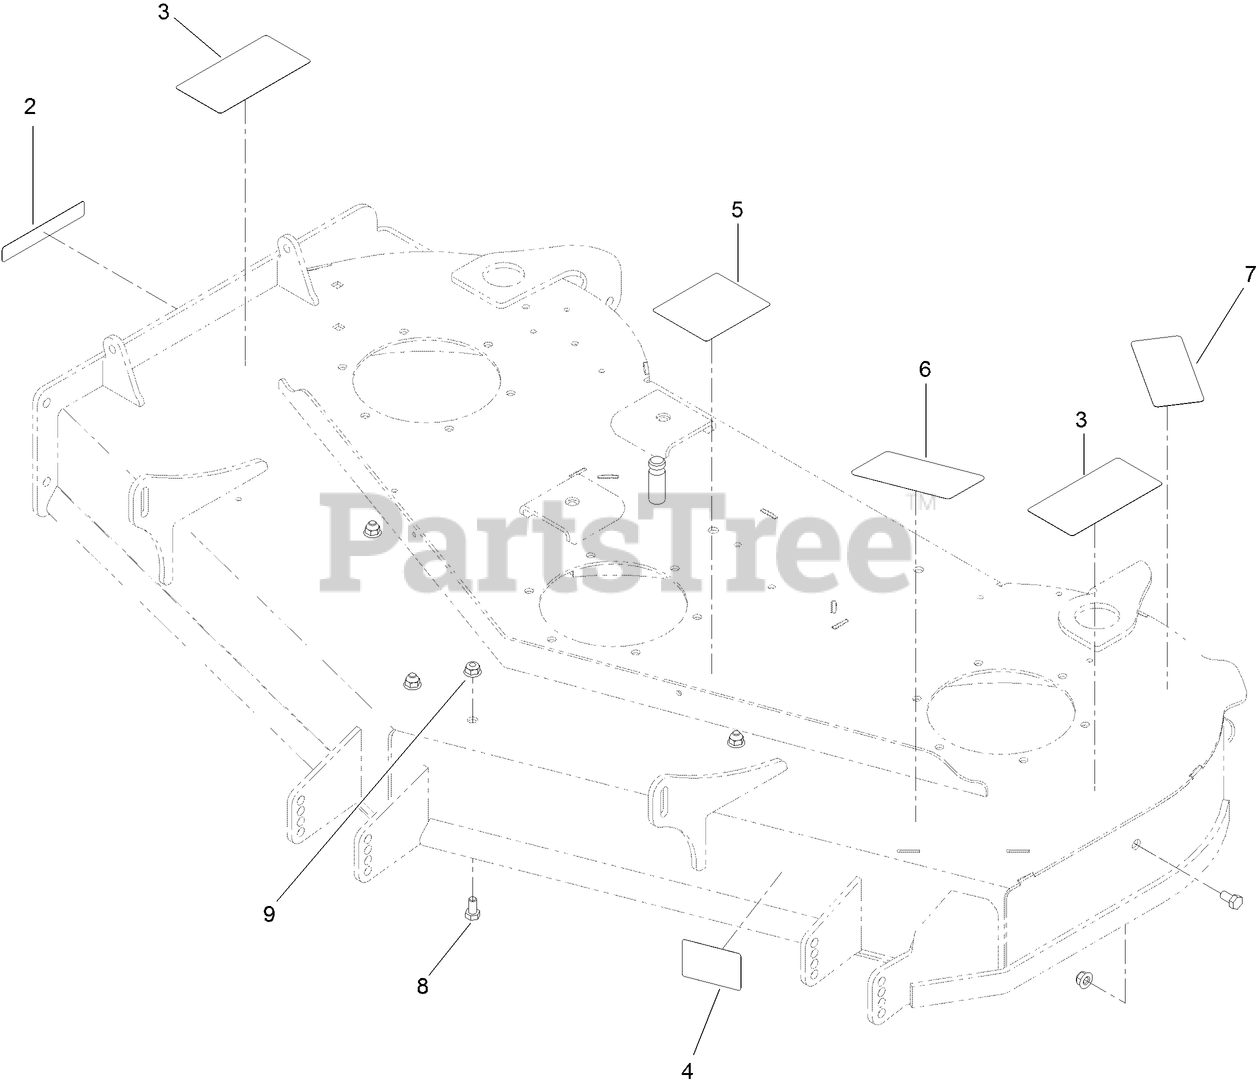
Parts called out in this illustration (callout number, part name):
2	DECAL-DANGER
3	DECAL-DANGER
4	DECAL-SCALP, ANTI
5	DECAL-ROUTING, BELT
6	DECAL-DECK, 48 INCH
7	DECAL-TORQUE, BLADE BOLT
8	SCREW-HH
9	NUT-HF, NI
